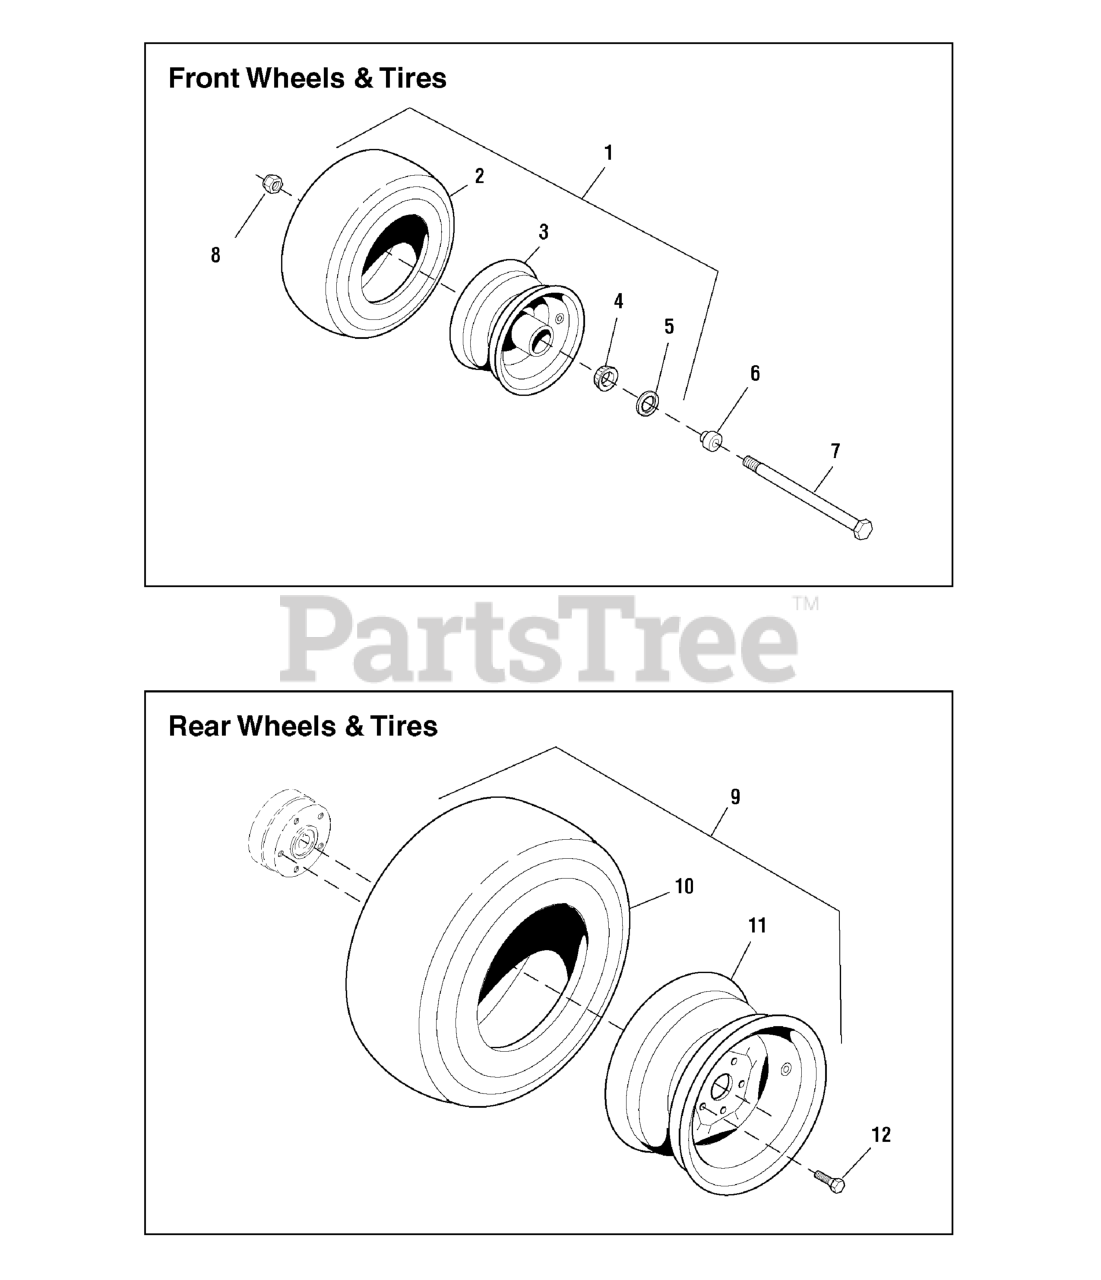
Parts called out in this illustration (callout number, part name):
1	WHEEL & TIRE ASSEMBLY, 13 x 5.0 x 6, Complete
2	TIRE, Front, 13 x 5.0 x 6
3	WHEEL ASSEMBLY, for 13 x 5.0 x 6 Tire, Complete
4	BEARING, Tapered Roller
5	SEAL, GREASE
6	ADAPTER, CASTER AXLE, CZ
7	BOLT, 1/2-13 x 7-1/2
8	NUT, 1/2-13 HEX NYLON LOCK
9	WHEEL & TIRE ASSEMBLY, 23 x 9.5 x 12, Complete
10	TIRE, Rear, 23 x 9.5 x 12
11	WHEEL ASSEMBLY, for 23 x 9.5 x 12 Tires
12	WHEEL LUG, 1/2 x 1-5/8
